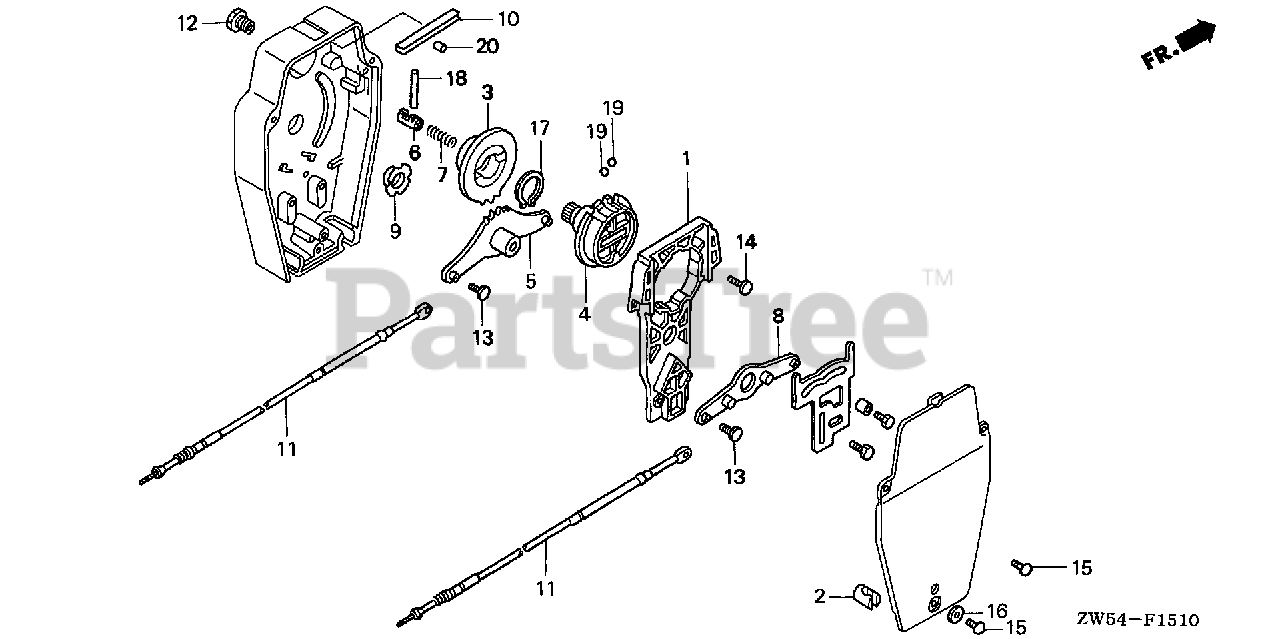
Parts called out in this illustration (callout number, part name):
1	FRAME ASSY., REMOTE CONTROL
3	WHEEL, CONTROL
4	SHAFT, HANDLE
5	ARM ASSY., SHIFT LINK
6	SHAFT, GEARSHIFT
7	SPRING, GEARSHIFT
8	ARM ASSY., THROTTLE LINK
11	CABLE, REMOTE CONTROL (10')
11	CABLE, REMOTE CONTROL (11')
11	CABLE, REMOTE CONTROL (12')
11	CABLE, REMOTE CONTROL (13')
11	CABLE, REMOTE CONTROL (14')
11	CABLE, REMOTE CONTROL (15')
11	CABLE, REMOTE CONTROL (16')
11	CABLE, REMOTE CONTROL (17')
11	CABLE, REMOTE CONTROL (18')
11	CABLE, REMOTE CONTROL (19')
11	CABLE, REMOTE CONTROL (20')
13	SCREW (8-32X3/8)
14	SCREW (10-32X5/8)
15	SCREW (10-32X5/8)
17	CIRCLIP (OUTER)
18	PIN, GEARSHIFT
19	BALL, STEEL
20	ROLLER, SHIFT CLICK
